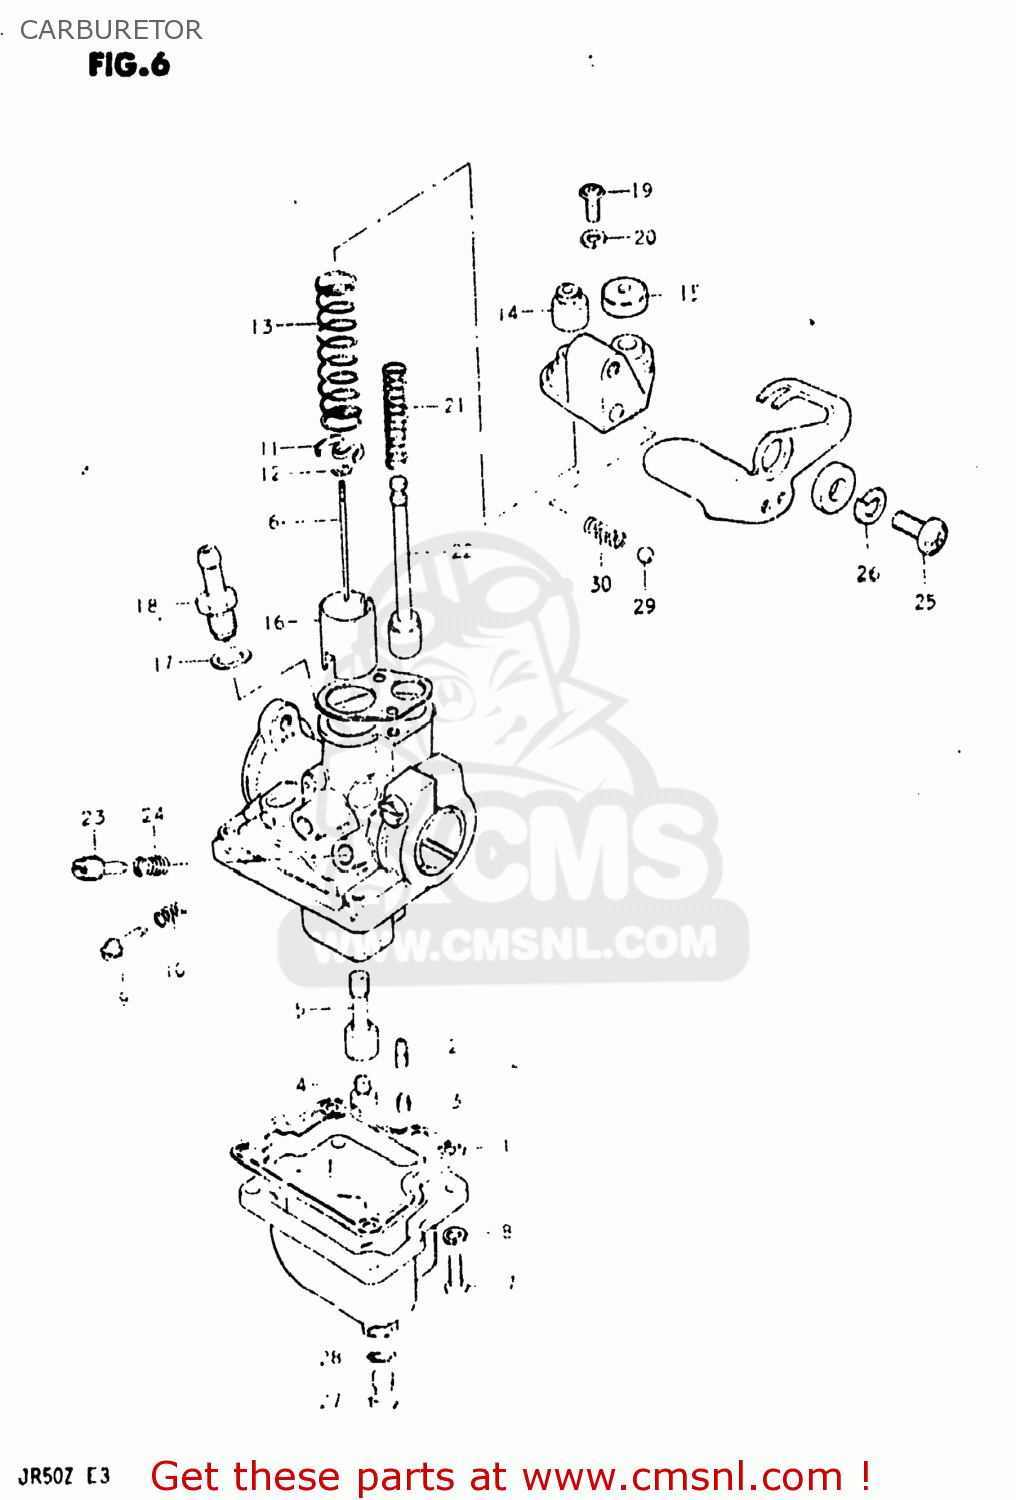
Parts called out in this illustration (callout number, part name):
1	GASKET,FLOAT CAHMBER (NAS)
2	JET,PILOT
3	JET
4	JET,MAIN
5	JET,NEEDLE
6	NEEDLE,JET
7	SCREW
8	LOCK WASHER
9	SCREW,THROTTLE STOP
10	SPRING
11	SEAT,THROTTLE VALVE SPRING
12	CLIP,NEEDLE
13	SPRING,THROTTLE VALVE
14	CAP
15	RUBBER,THROTTLE VALVE CAP
16	VALVE,THROTTLE
17	GASKET (NAS)
18	VALVE ASSY,NEEDLE
19	SCREW 4X10
20	LOCK WASHER
21	SPRING
22	VALVE,STARTER
23	SCREW,AIR
24	SPRING
25	SCREW 6X12
26	LOCK WASHER
27	PLUG
28	GASKET,DRAIN,PLUG (NAS)
29	BALL,STARTER SHAFT
30	SPRING,STARTER SHAFT
